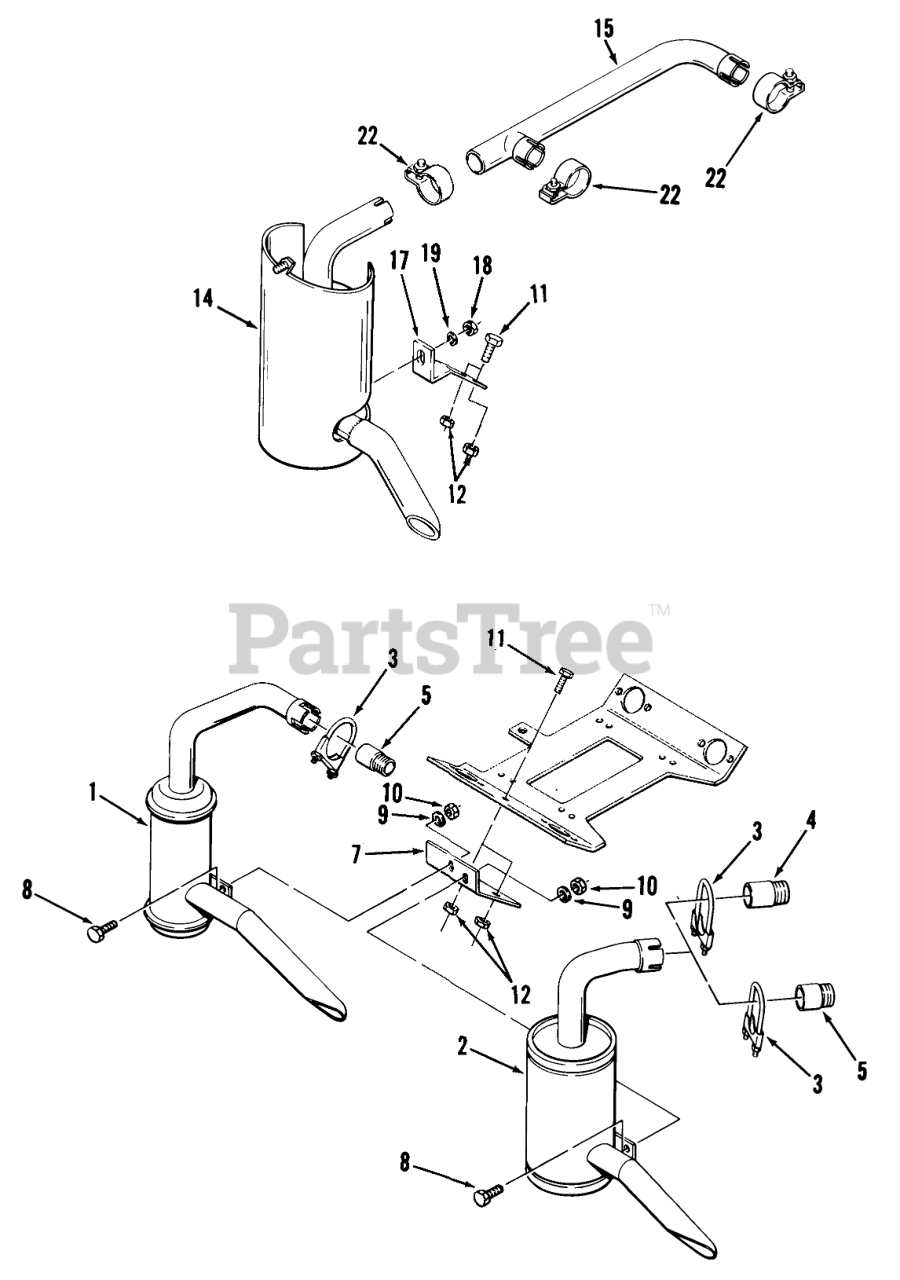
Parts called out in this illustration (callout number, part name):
1	ASSY-MUFFLER
2	MUFFLER ASSEMBLY
3	ASSY-MUFFLER CLAMP
4	NIPPLE
5	NIPPLE- 1X2 SPECIAL
7	BRACKET-MUFFLER MTG
8	H H C S
9	Washer
10	Nut
11	Bolt
12	Nut
14	Muffler C-175 Twin Only
15	MANIFOLD-EXHAUST
17	BRACKET-MUFFLER
18	Nut
19	LOCKWASHER
22	CLAMP-MUFFLER
